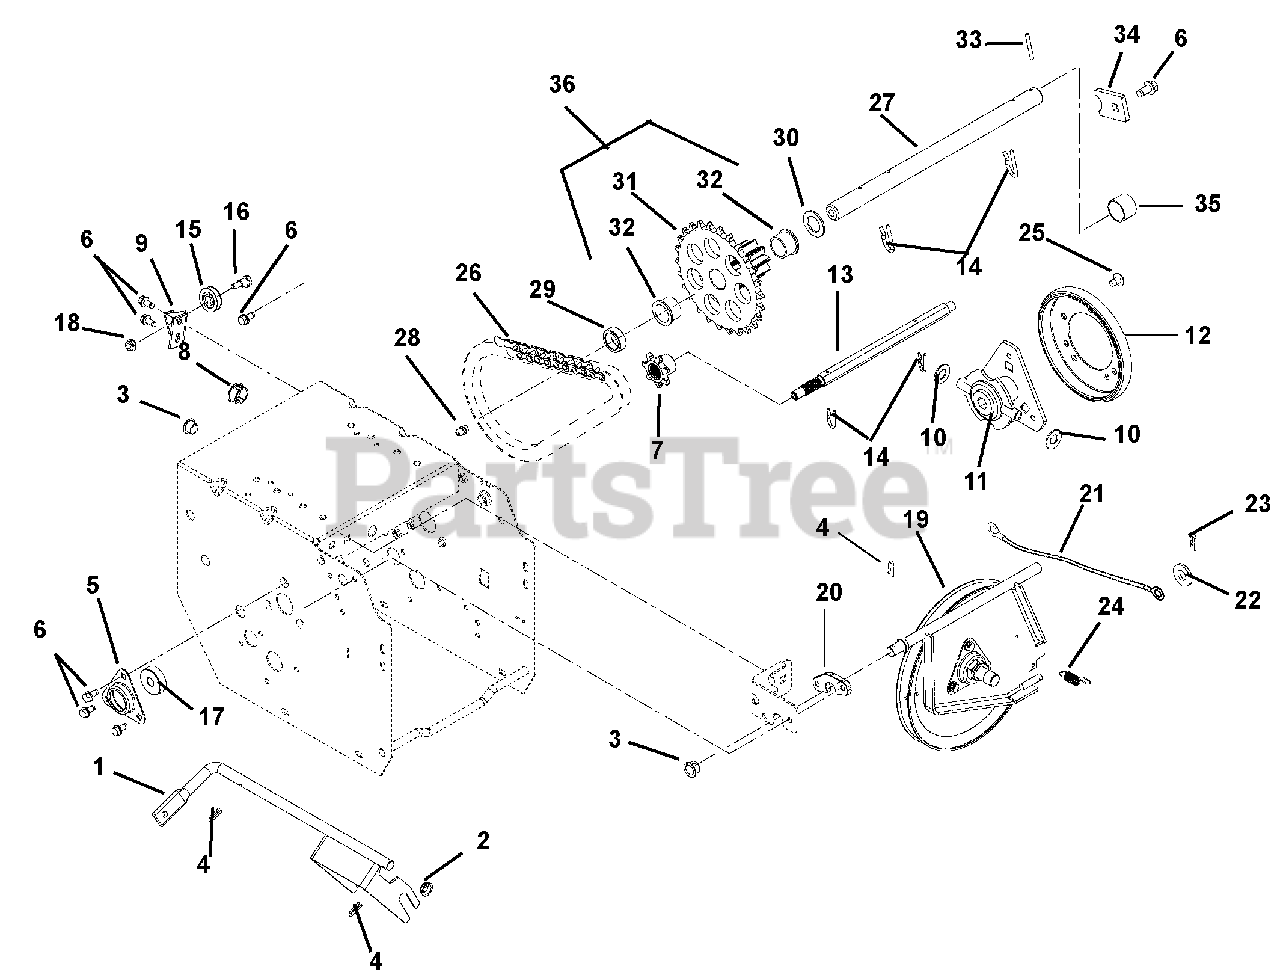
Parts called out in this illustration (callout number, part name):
1	Weldment, Shift Fork
2	Bushing, Polyliner-.50 Snap-in
3	Bushing, Polyliner-.50 Split
4	Clip, Spring
5	2 Flange, Bearing
6	Screw, Tapping Hex Washer Head .25-20 x .50
7	Spocket, Pinion, 7 Tooth w/Spline
8	Plug, Hole- .875" Nylon (017, 018, 023, 304, 307, 308, 309, 311)
9	Bracket, Cable Pulley
10	Washer, Flat Steel .505 x 1.00 x .062
11	Carrier, Drive Disc
12	Friction Disc
13	Hex Shaft w/spline
14	Pin, Spring Clip
15	Pulley, Cable
16	Bolt, Shoulder .375 x .375 x .25-20
17	Bearing, Ball
18	Nut, Locking Top Flange .25-20
19	Plate, Swing Assembly
20	Spacer, Swing Gate
21	Cable, Traction - Tractor
22	Washer, Flat-Steel .344 x .688 x .065
23	Pin, Hair Internal .08 x .18 x 1.18
24	Spring, Extension
25	Screw, Tapping Serrated Round Head Torx .31-18 x .50
26	Chain, #41, 32 Pitches
27	Shaft, Pinion
28	Zerk, Fitting .25 x .125 Drive-In
29	Bushing, Sleeve
30	Washer, Flat Steel .630 x 1.005 x .062
31	Pinion and Sprocket (included in item 36)
32	Bushing, Flange (included in item 36)
33	Pin, Groove .125 x 1.00 Type E Alloy
34	Tab, Anti-Rotation
36	Pinion and Sprocket w/Bushings (includes items 31 and 32)
